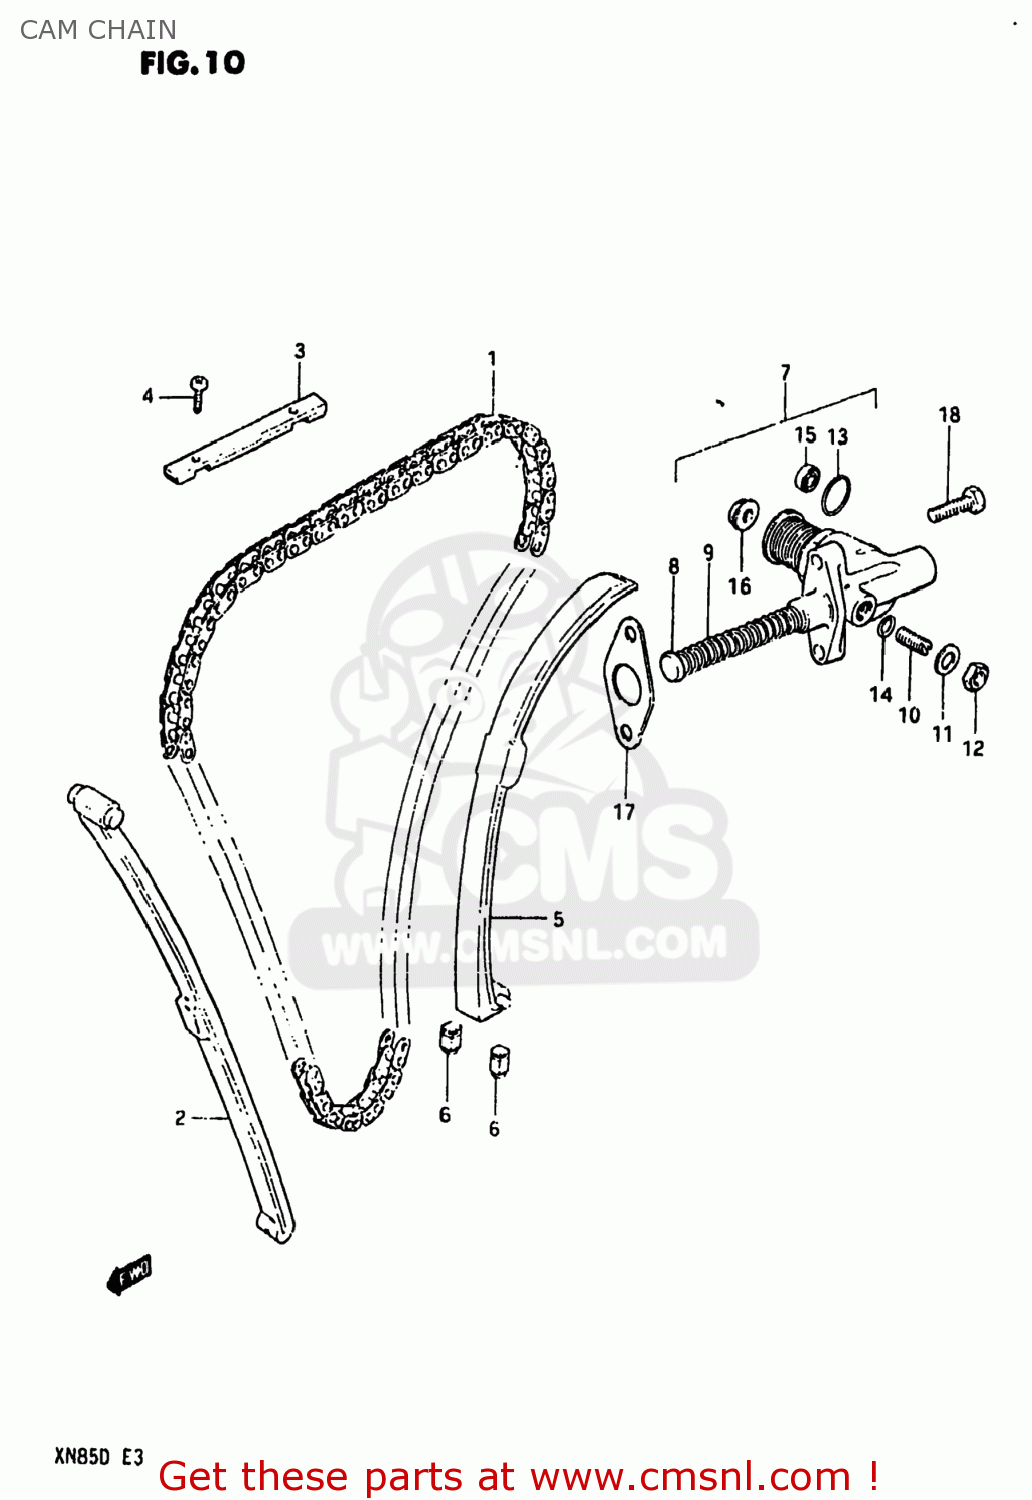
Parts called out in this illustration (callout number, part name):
1	CHAIN,CAMSHAFT DRIVE(120L)
2	GUIDE,CAM CHAIN
3	GUIDE,CAM CHAIN
4	SCREW
5	TENSIONER,CAM CHAIN
6	CUSHION,CAM CHAIN TENSIONER
7	ADJUSTER,CAM CHAIN TENSIONER
8	ROD,PUSH
9	SPRING
10	SCREW
11	WASHER
12	NUT
13	O RING(D:2.4,ID:20.8)
14	O RING(D:1.9,ID:5.7)
15	SEAL,OIL(10X16X4)
16	NUT
17	GASKET,TENSIONER ADJUSTER (MCA)
18	SCREW (6X25)
